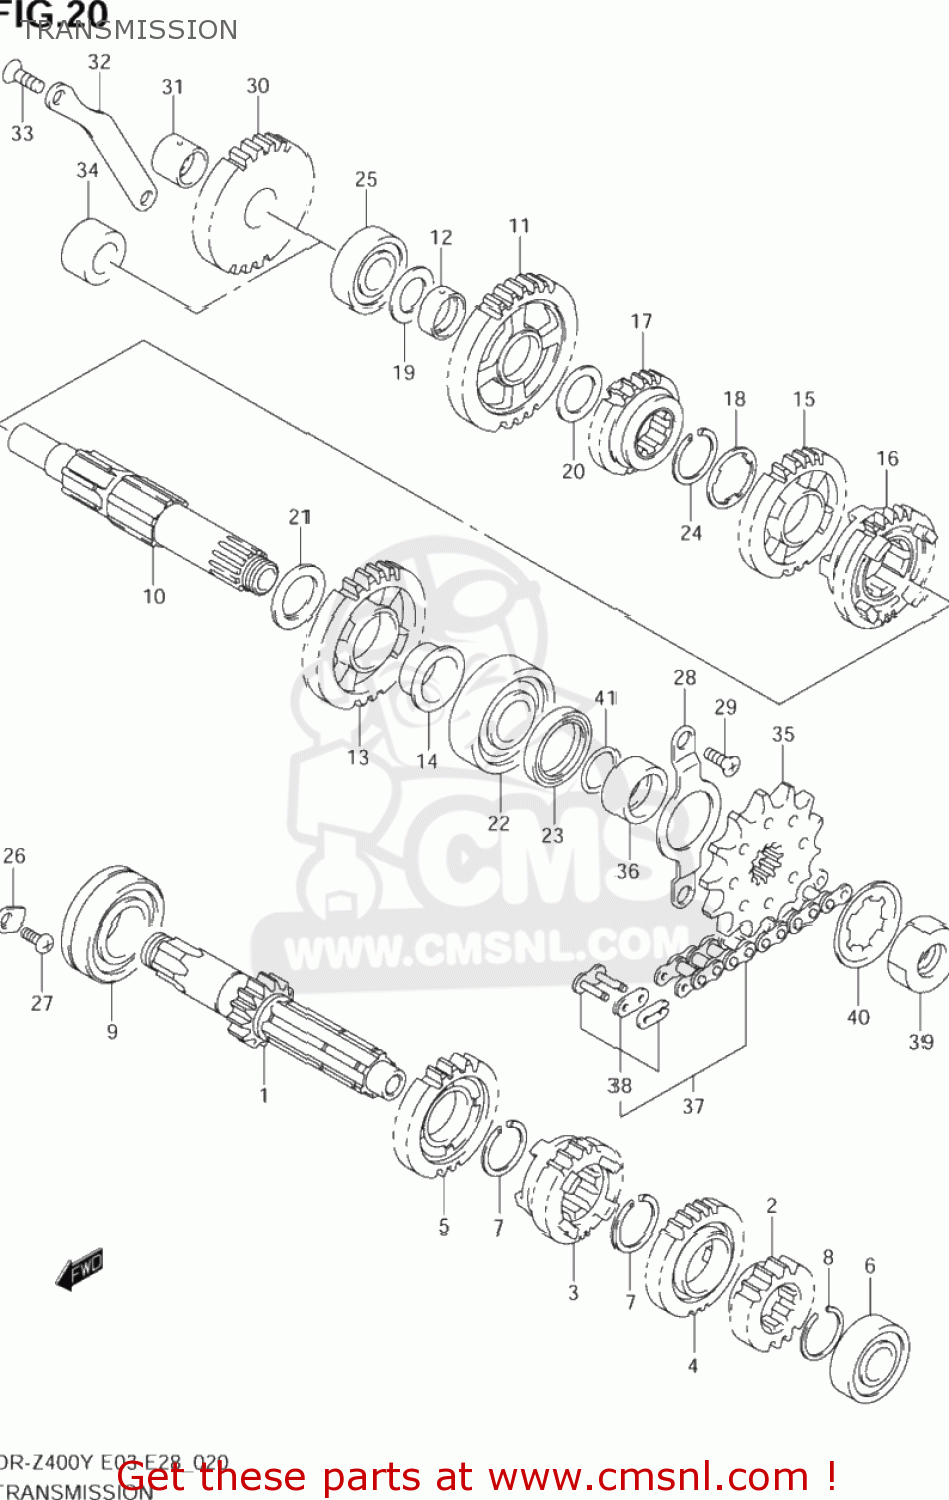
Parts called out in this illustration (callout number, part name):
1	SHAFT,COUNTER(NT:14)
2	GEAR,2ND DRIVE(NT:15)
3	GEAR,3RD DRIVE(NT:16)
4	GEAR,4TH DRIVE(NT:22)
5	GEAR,5TH DRIVE(NT:22)
6	BEARING(17X40X12)
7	CIRCLIP
8	CIRCLIP
9	BEARING(25X52X15)
10	SHAFT,DRIVE
11	GEAR,1ST DRIVEN(NT:32)
12	BUSH,1ST DRIVEN GEAR
13	GEAR,2ND DRIVEN(NT:26)
14	BUSH,2ND DRIVEN GEAR
15	GEAR,3RD DRIVEN(NT:22)
16	GEAR,4TH DRIVEN(NT:24)
17	GEAR,5TH DRIVEN(NT:19)
18	WASHER,LOCK
19	SHIM(17X30X1)
20	SHIM(20X30X1)
21	SHIM(22X34X1)
22	BEARING(22X56X16)
23	SEAL,OIL(30X40X6)
24	CIRCLIP
25	BEARING(17X40X12)
26	RETAINER
27	BOLT(6X12)
28	RETAINER,DRIVE SHAFT OIL SEAL
29	SCREW(6X14)
30	GEAR,KICK STARTER IDLE
31	BUSH,KICK STARTER IDLE GEAR
32	RETAINER,KICK IDLE GEAR
33	SCREW ,6X16
34	SPACER(17X30.5X16.3)
35	SPROCKET,ENGINE(NT:14)
36	SPACER,ENGINE SPROCKET
37	CHAIN ASSEMBLY,DRIVE RK520
38	JOINT SET,CHAIN
39	NUT
40	WASHER,LOCK
41	O RING(D:2.5,ID:21)
